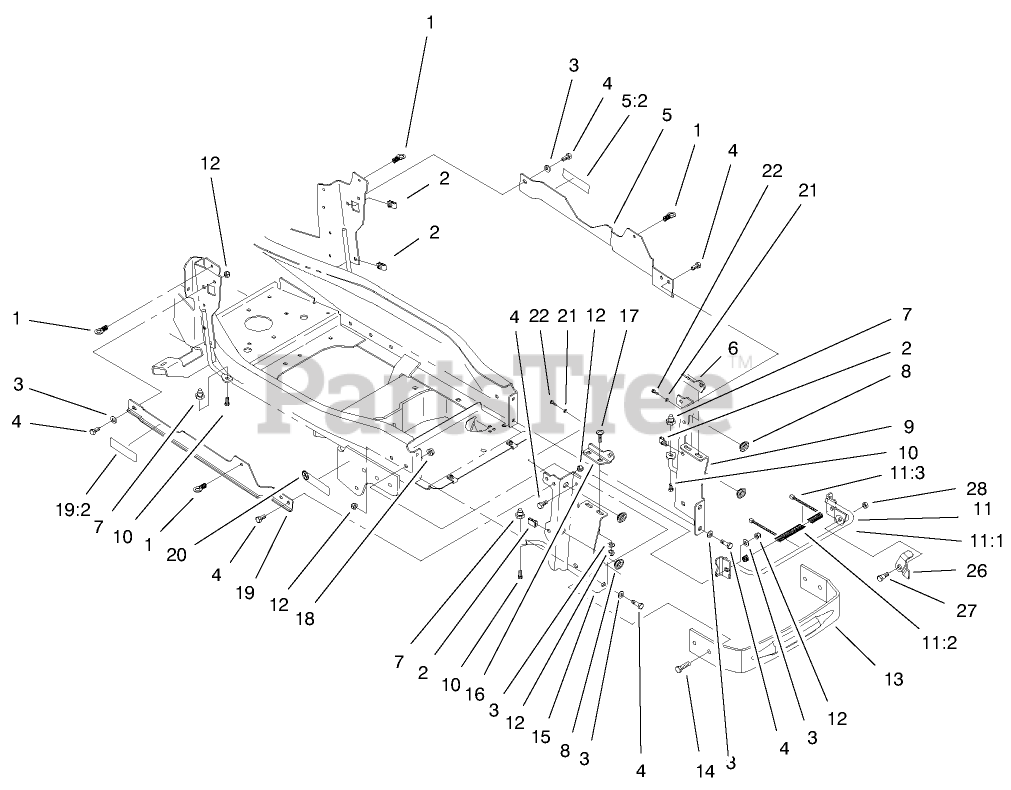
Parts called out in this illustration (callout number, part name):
1	LATCH ASM
3	WASHER-PLAIN
4	SCREW-HH
5	SUPPORT / DECAL ASM
5	SUPPORT ASM
5:2	DECAL - WARNING
5:2	DECAL-WARNING
6	BRACKET-HINGE, LOWER LH
7	MOUNT-SIDEPANEL
8	GROMMET
10	SCREW-PLASTITE
11:2	COVER-BRACE
11:3	TIE-CABLE
12	NUT-LOCK, NI
14	SCREW-HH
15	SUPPORT-HOOD, RH
16	BRACKET-HINGE, LOWER RH
17	SCREW-CARR
18	NUT-LOCK, NI
19	SUPPORT ASM
19:2	DECAL - WARNING
19:2	DECAL-WARNING
20	DECAL-ATTACH A-MATIC
21	WASHER-FLAT
22	SCREW-THD FORM, HWH
26	LEVER-PROP, HOOD
27	BOLT-SHOULDER,HFH
28	NUT-LOCK, NI
